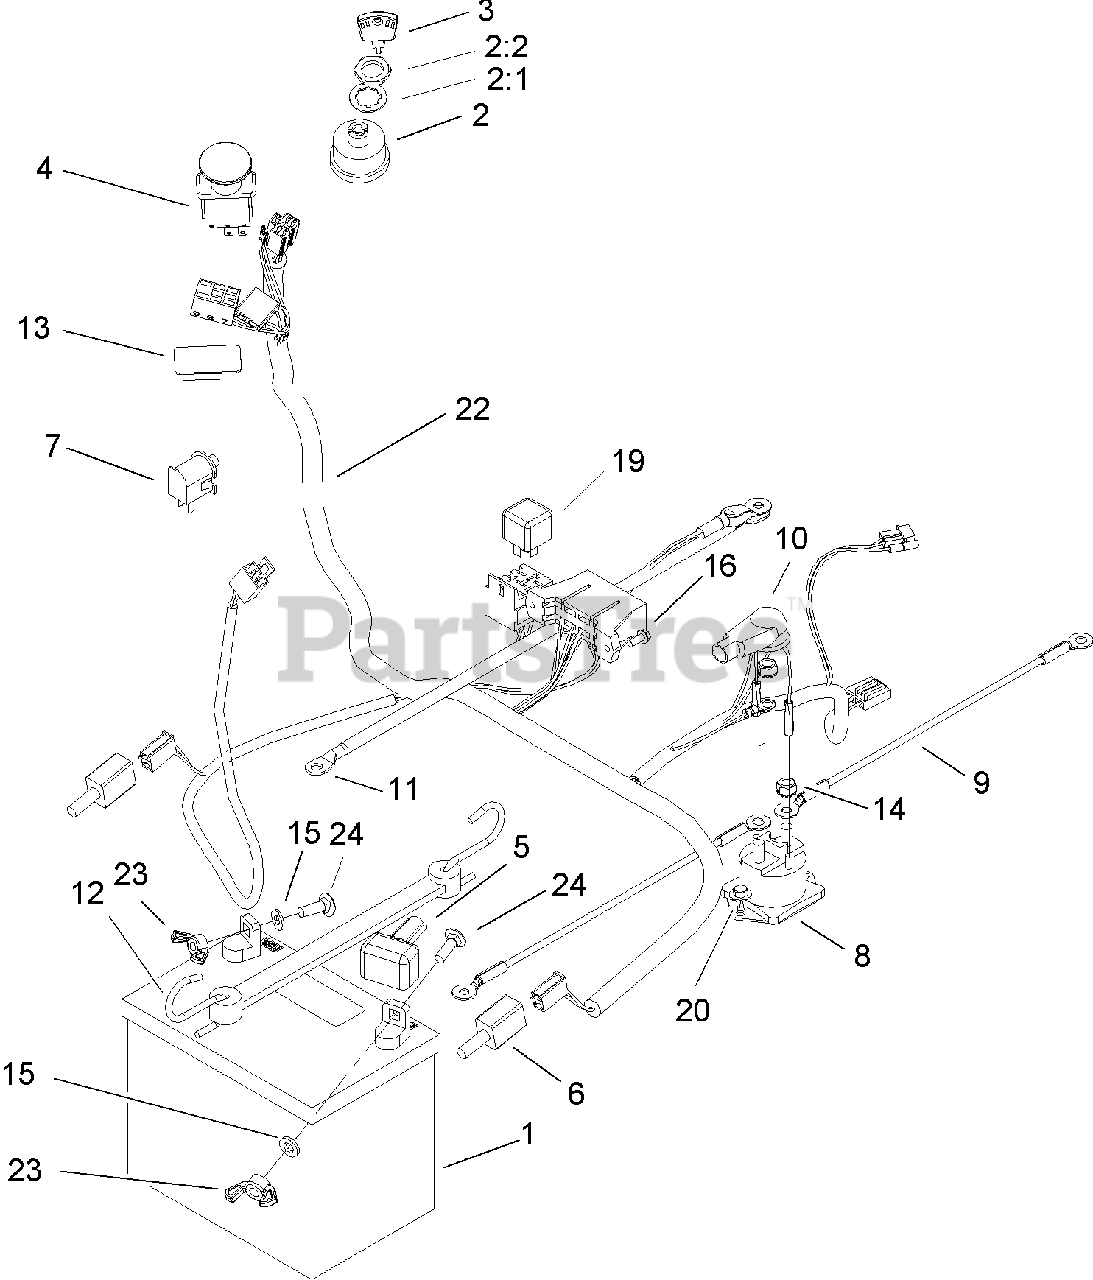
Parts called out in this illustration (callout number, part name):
1	BATTERY-DRY
2	Key Switch ASM
2:1	WASHER-TOOTH
4	SWITCH-PTO
5	BOOT-TERMINAL
7	SWITCH-BAIL
9	WIRE ASM
10	BOOT-INSULATOR, TERMINAL
12	HOLDDOWN-BATTERY
14	NUT-KEPS
15	WASHER-FLAT
16	SCREW-TAPTITE
20	SCREW-HHF
22	HARNESS-WIRE, WITH LIGHTS
24	SCREW-CARR
